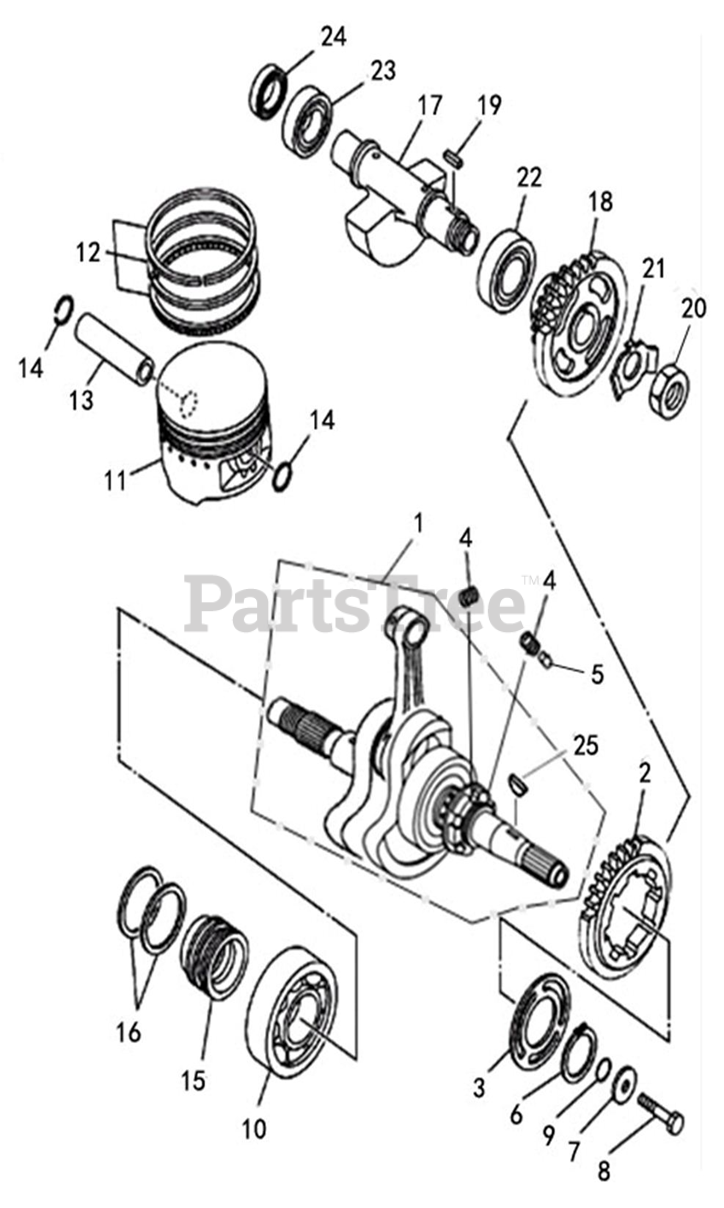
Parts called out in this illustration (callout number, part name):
1	CRANKSHAFT
2	DRIVING GEAR BALANCE SHAFT
3	OUTER BALANCE GEAR LOC PLATE
4	BALANCE GEAR BUFFER SPRING
5	BALANCE GEAR SPACER PIN
6	CIRCLIP FOR SHAFT
7	WASHER 10 x 32 x 5
8	HEX FLANGE BOLT M10 x 1.25 x 40
9	O-RING 16X3
10	BEARING 6307
12	PISTON RING SET
13	PISTON PIN
14	PISTON PIN CLIP
15	SEALING RING BUSHING
16	SEALING RING
17	BALANCE SHAFT ASSEMBLY
18	DRIVEN GEAR BALANCE SHAFT ASM
20	HEX NUT M18X1
21	TAB WASHER A
22	BEARING 6305
23	BEARING 6304
24	OIL SEAL 20X30X7
